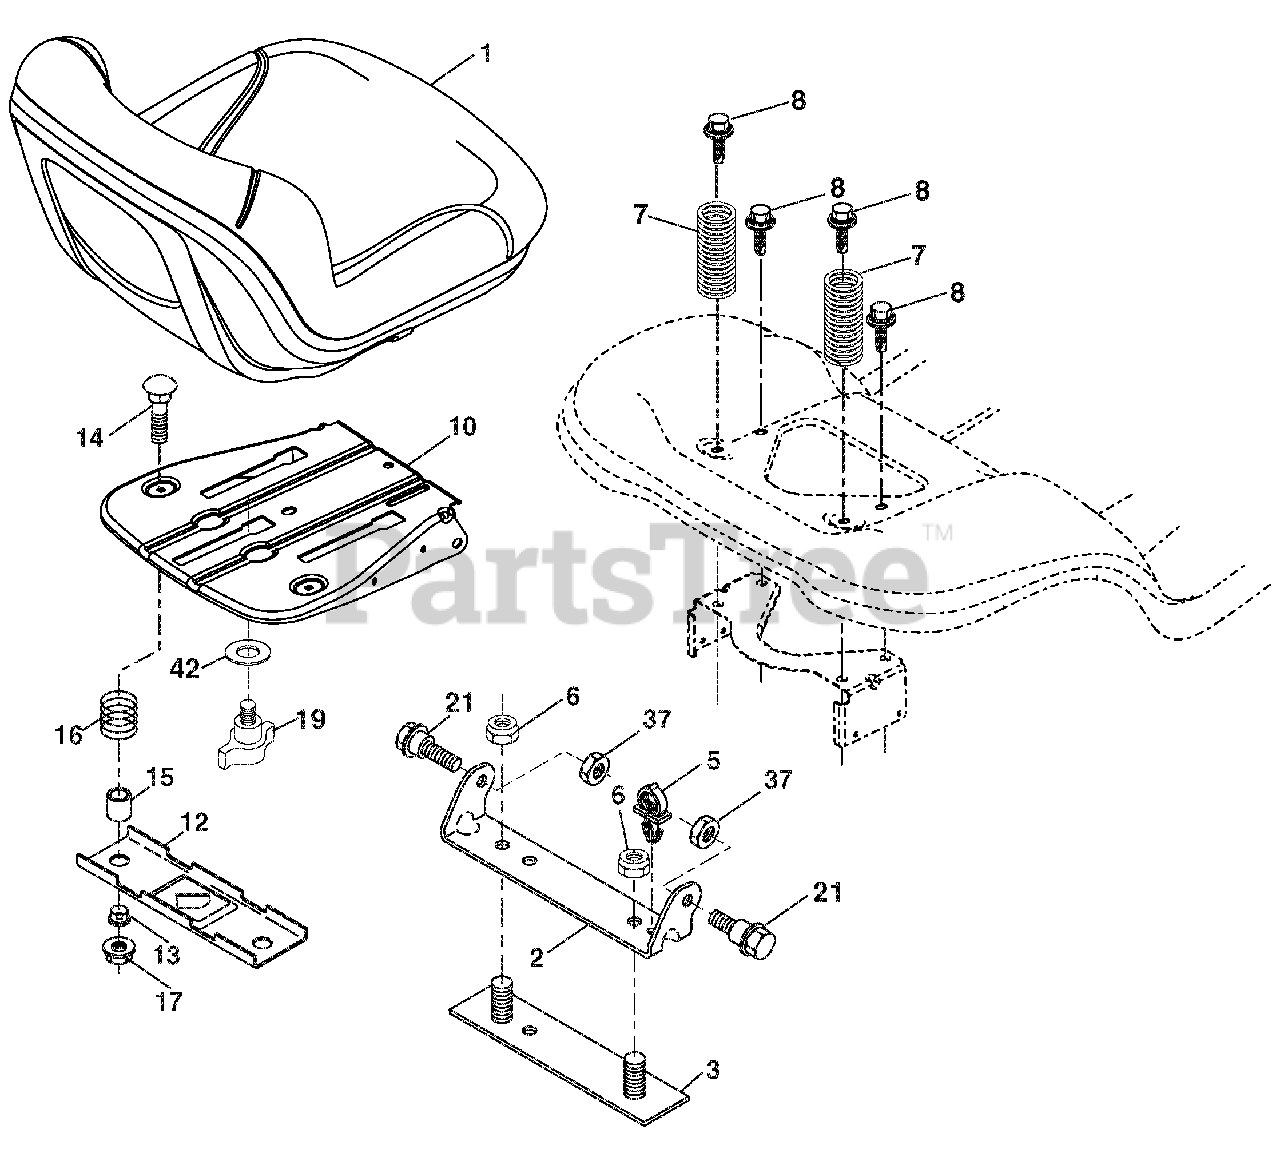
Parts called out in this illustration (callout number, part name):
1	SEAT.TA110.BLACK.ARIENS
2	BRACKET.PIVOT.FENDER.2002
3	STRAP ASM.FENDER.94
5	CLIP.PUSH-IN.HINGED
6	Locknut, Washer Insert 3/8-16
7	SPRING.SEAT.CPRSN.2.250.BLK.ZI
8	BOLT.5/16-18UNCX3/4 W/SEMS.BLK
10	PAN ASM.SEAT.SHORT.LT.TEX
12	BRACKET.MNT.OPC.SW.SEAT.TEX LT
13	BUSHING.SNAP.BLK.NYL..50 ID.
14	BOLT.RDHD.SHT.NK.1/4-20X1-1/2
15	SPACER.SPLIT..28X.96.YEL.ZINC
16	SPRING.CPRSN.PLATE.SW.1.310.GA
17	NUT.LOCK.1/4 LGE.FLG.GR.5.ZINC
19	KNOB.SEAT ADJ.3/8-16"TEX
21	BOLT.SHLD.5/16-18 UNC-2A.BLK D
37	Locknut, Washer Insert 5/16-18
42	WASHER.CUP.SEAT.TEX LT
